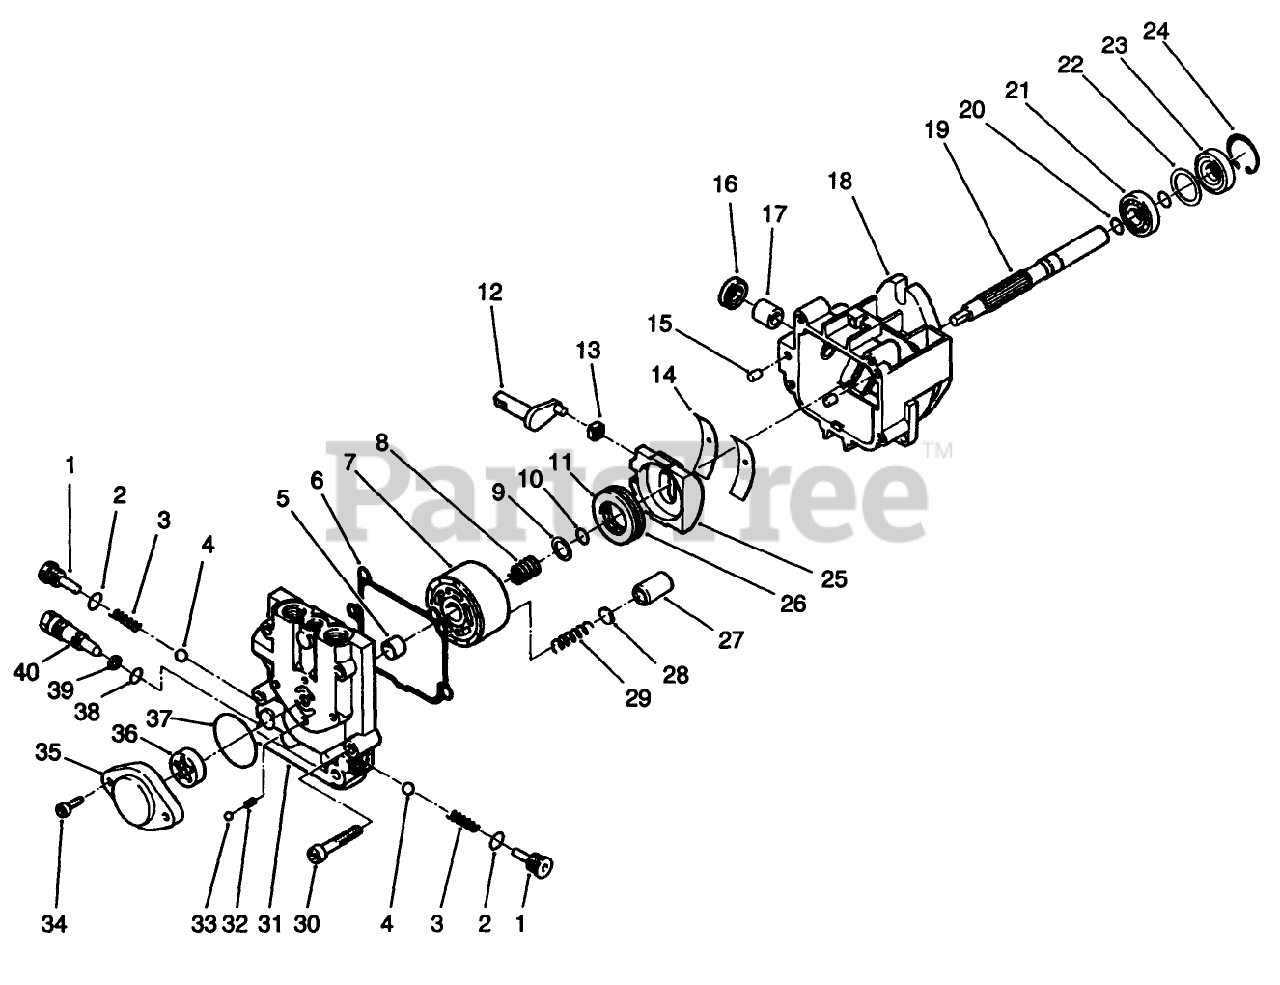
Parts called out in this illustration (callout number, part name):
1	CHECK VALVE KIT
2	Seal-O-Ring
4	Ball
5	Journal-Bearing
6	Gasket-End Cap
9	Washer
11	Plate-Thrust
12	Arm-Trunion
13	Guide-Slot
14	Cradle-Bearing
16	Seal-Lip
17	Journal-Bearing
19	Shaft
21	Bearing-Ball
23	Seal-Lip
25	Swashplate Assembly
26	Roller-Thrust
29	Spring-Piston
32	Ball
35	Housing-Charge Pump
36	Gerotor Assembly
37	Seal-O-Ring
38	Seal-O-Ring
39	Ring-Back-Up
40	Valve-Bypass
